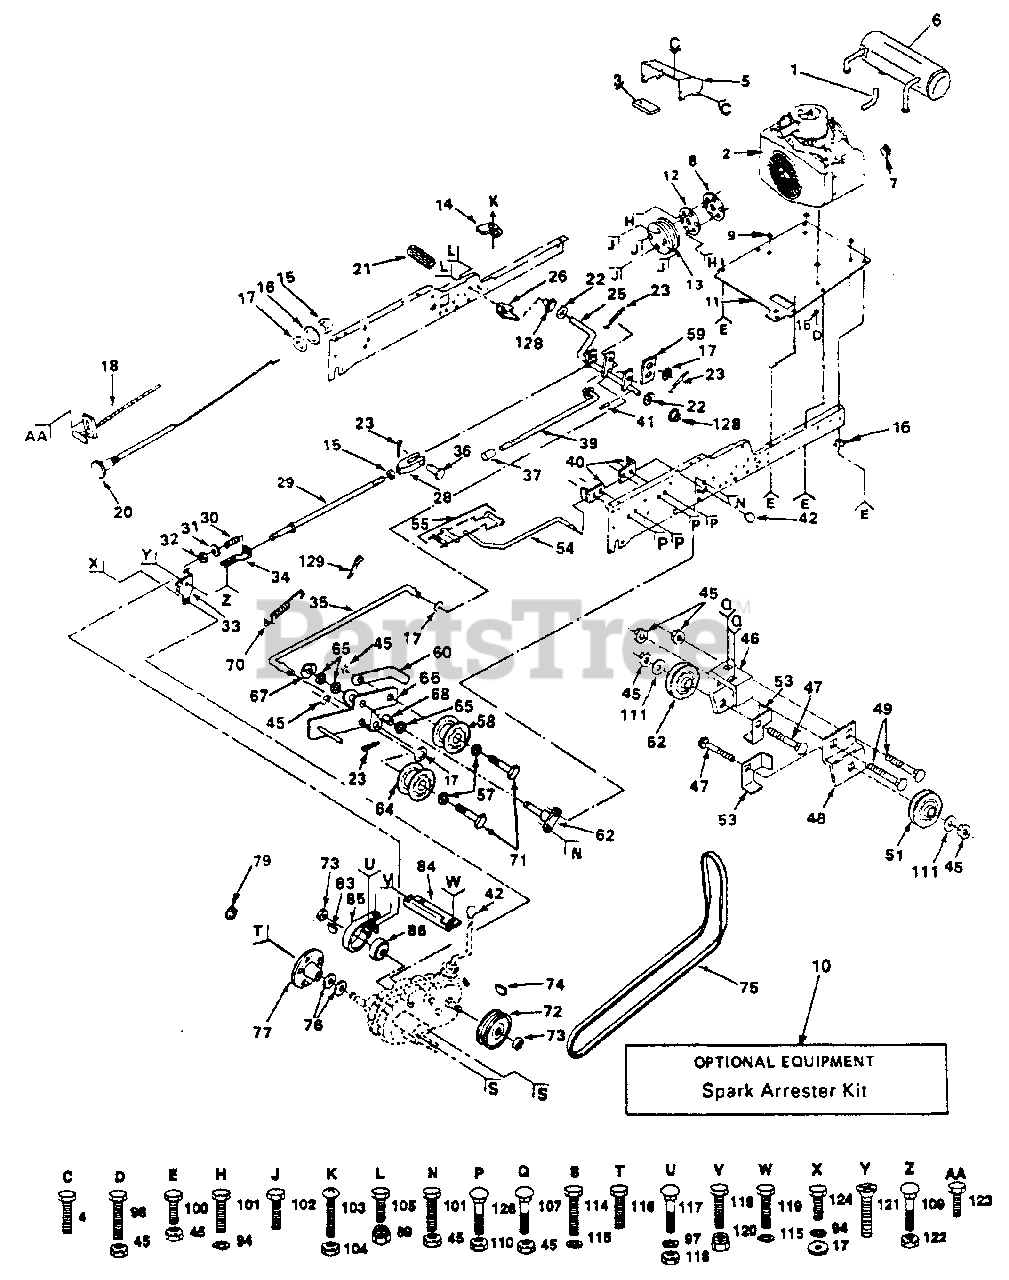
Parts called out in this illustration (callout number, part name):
1	Exhaust Tube Outlet
2	Engine-18HP Kohler M18QS Type 24644
3	Duct, Lower Assembly
4	Screw, Hex Thd. Cut 1/4-20 x 1/2
5	Duct, Exhaust, Upper
6	Muffler, Exhaust
7	Plug, Oil Drain
8	Chaff Guard
10	Spark Arrester Kit
11	Base, Engine
13	Pulley, Ground Drive
14	Actuator, Switch, Interlock
15	Nut, Hex 3/8-24
16	Washer, Lock Ext. Tooth 3/8
17	Washer 13/32 x 13/16 x 16 Gauge
18	Control, Throttle
20	Control, Choke
21	Cover, Pedal
22	Washer 25/32 x 1-1/4 x 16 Gauge
23	Pin, Cotter 3/32 x 3/4
25	Shaft, Foot Pedal
26	Bracket, Interlock
29	Rod, Brake
30	Spring, Compression
31	Washer 13/32 x 1 x 14 Gauge
32	Locknut 3/8-24
33	Bracket, Brake
34	Guide, Rod, Brake
35	Rod, Clutch
36	Pin, Clevis
37	Cap, Plunger
39	Rod, Parking Brake
40	Bracket, Rod, Shift
41	Pin, Roll 3/16 x 1-1/4
45	Locknut 3/8-16
46	Bracket, V-Pulley, Drive, Mule
47	Bolt, Carriage 3/8-16 x 1-3/4
48	Bracket, Idler, Flat
49	Bolt, Carriage 3/8-16 x 3/4
51	Idler, Flat
52	Pulley, Idler
53	Keeper, Belt
54	Rod, Shift, Hi-Lo
55	Connecting Link, Spring Clip
57	Washer 13/32 x 7/8 x 13 Gauge
58	Idler, Flat
59	Retainer, Spring
60	Retainer, Belt
62	Bracket Assembly, Clutch
64	Idler, Grooved
65	Washer, Hardened
66	Bracket, Clutch w/Bearing
67	Klip, Ring
68	Bearing, Idler
70	Spring, Extension
71	Bolt, Hex 3/8-16 x 1-3/4
72	Pulley, Transaxle
73	Locknut 1/2-20
74	Key, Woodruff 3/16 x 5/8
76	Washer, Thrust, Axle
77	Bushing Assembly and Wheel Hub
79	Klip, Ring
83	Key, Woodruff #9 (3/16 x 3/4)
84	Bracket, Support, Transaxle
85	Band, Brake
86	Drum, Brake
89	Nut, Crownlock 1/4-20
94	Washer, Lock 3/8
97	Washer, Lock 1/4
98	Bolt, Hex 3/8-16 x 1-3/4
100	Bolt, Hex 3/8-16 x 3/4
101	Bolt, Hex Head 3/8-16 x 1 Grade 5
102	Screw, Hex 5/16-18 x 1
103	Screw, Fin #10-24 x 1
104	Locknut #10-24
105	Bolt, Hex Head 1/4-20 x 3/4
107	Bolt, Carriage 3/8-16 x 3/4 Grade 5
109	Bolt, Carriage 5/16-18 x 3/4
110	Locknut 5/16-18
111	Washer 13/32 x 1 x 12 Gauge
114	Bolt, Hex 7/16-14 x 1-1/4
115	Washer, Lock 7/16
116	Bolt, Hub
117	Bolt, Carriage 1/4-20 x 5/8
118	Nut, Hex 1/4-20
119	Bolt, Hex 7/16-14 x 1
120	Nut, Crownlock 7/16-14
121	Screw, Mach. Undrcut. Flat Head 3/8-16 x 3/4
122	Locknut 5/16-18
123	Screw, Hex 1/4-20 x 1/2
124	Bolt, Hex 3/8-16 x 7/8
126	Bolt, Carriage 5/16-18 x 3/4
